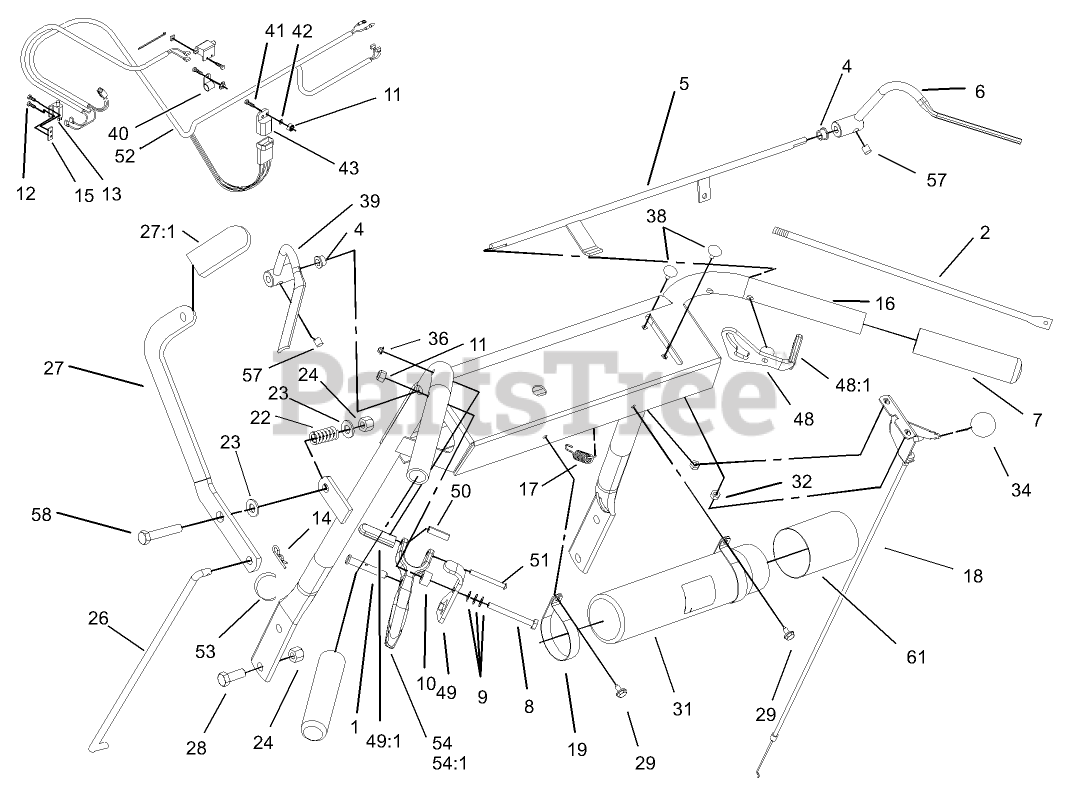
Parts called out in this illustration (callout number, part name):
1	PIN-CLEVIS
2	Linkage-Wheel, Drive
4	BUSHING-NYLON
5	ROD-CONTROL, OPERATOR PRESENCE
6	LEVER-RH
7	Grip-Handle
8	SCREW-HH
9	WASHER-SPRING
10	SPACER
11	NUT-LOCK, NI
12	SCREW-PPH
13	SWITCH-OPEN, NORMALLY
14	PIN-COTTER
15	PLATE-TAPPED
16	HANDLE ASM
17	SPRING-EXTENSION
18	Cable-Control, Throttle
19	CLAMP-R
22	SPRING-COMPRESSION
23	WASHER-FLAT
24	NUT-LOCK, NI
26	Linkage-Blade, Upper
27	LEVER ASM
27:1	GRIP-LEVER
28	SCREW-HH
29	SCREW-HWHTF
31	TUBE-MANUAL
32	NUT-LOCK, NI
34	KNOB-BALL
38	BOLT-CARR
39	LEVER-LH
40	CLIP-LOOM
41	SCREW-HH
42	WASHER-FLAT
43	MODULE-INTERLOCK
48	RH THUMB LATCH ASM
48:1	GRIP-LATCH
49	LH THUMB LATCH ASM
49:1	GRIP-LATCH
50	PIN-ROLL
51	PIN-LEVER, DRIVE
52	Harness-Wiring
53	Clip-Cable
54	DRIVE LEVER ASM
54:1	GRIP-LEVER, DRIVE
57	SCREW-SET
58	SCREW-HH
61	CAP-HOUSING
